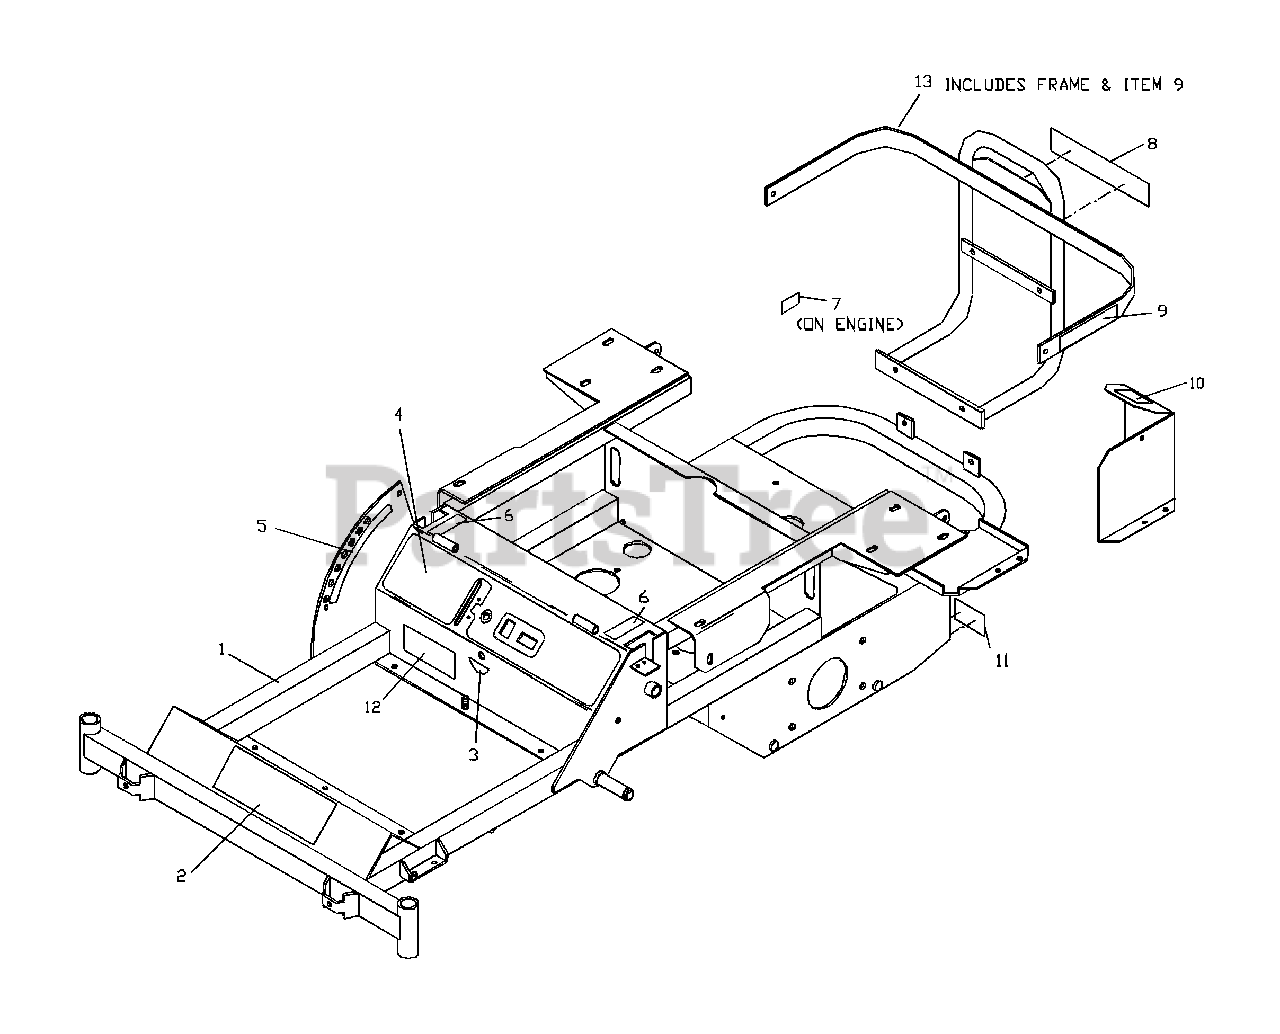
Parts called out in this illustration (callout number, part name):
1	FRAME W/DECALS (KAWASAKI)
1	FRAME W/DECALS (KOHLER)
2	DECAL, HUSQVARNA
3	DECAL, FUEL VALVE
4	DECAL, CONSOLE (KAWASAKI)
4	DECAL, CONSOLE (KOHLER)
5	DECAL, LOCATOR
6	DECAL, MOTION CONTROL
7	DECAL, EXHAUST
8	DECAL. HUSQVARNA
9	DECAL, BATTERY
10	DECAL, PROP. 65
11	DECAL, DANGER
12	DECAL, NASCAR
13	ENGINE GUARD W/DECALS
